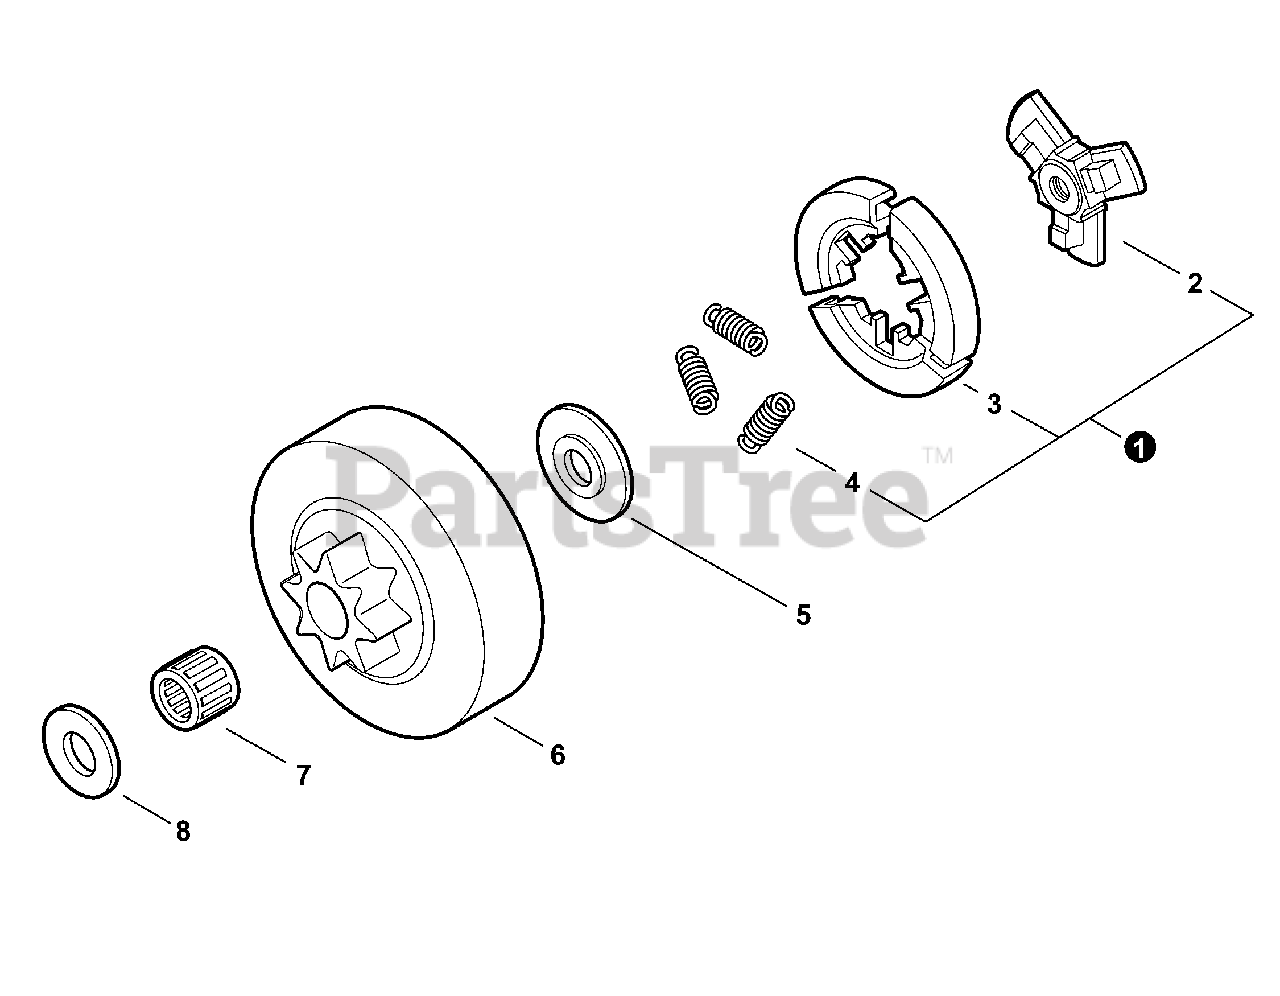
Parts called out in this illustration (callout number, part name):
1	CLUTCH ASSY
2	HUB, CLUTCH
3	SHOE SET, CLUTCH (3PCS)
4	SPRING, CLUTCH
5	PLATE, CLUTCH
6	DRUM, CLUTCH 3/8"
7	BEARING, NEEDLE 10
8	WASHER 10.2×24.5×1.2
